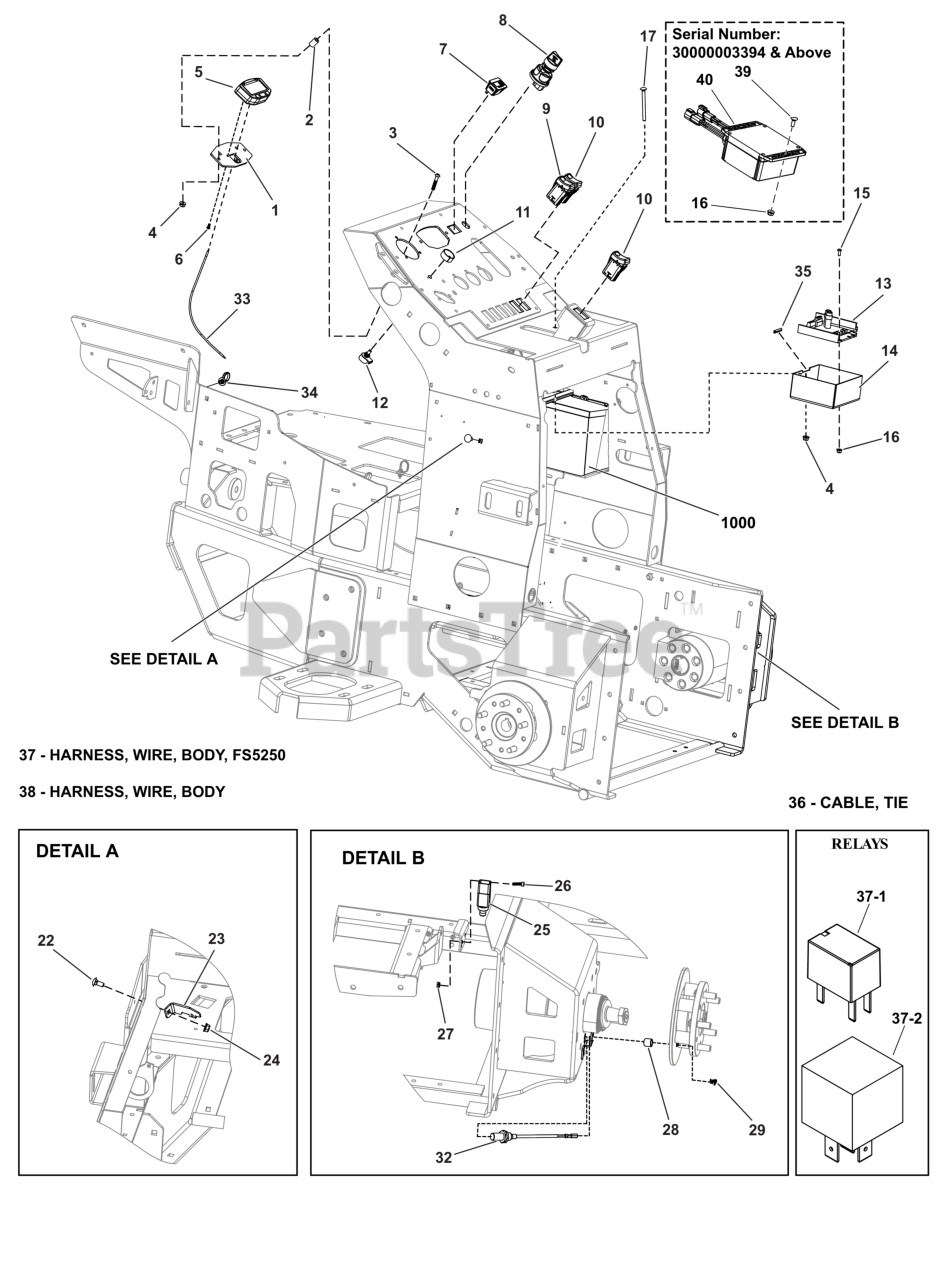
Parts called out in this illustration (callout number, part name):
1	MOUNT, DISPLAY
2	SPCR-SS, 304 .252 X .500 X .750
3	SCR-CAP, SBH .250-20 X 1.500" SS188
4	NUT-HEX-NYLK, FLG .250"-20 SS188
5	DISPLAY, CONSOLE
6	SCR-CAP, SBH M4-0.7 X 10MM SS188
7	METER, TACH/HOUR INDUCTIVE PICKUP
8	SWITCH, IGNITION, IP67 RATED, 3 POS
9	SWITCH, PANEL MOUNT, ON(MOM)-OFF
10	SWITCH, PANEL MOUNT ROCKER ON-OFF
11	KNOB, DART SPEED CONTROL
12	POTENTIOMETER, SPEED CONTROL 5K OHM
12	POTENTIOMETER, 10K OHM, 11 DETENT
13	DRIVE, GEARMOTOR, 12V, 17.5" WIRE LENGTH
14	COVER, DART CONTROLLER
15	SCR-CAP, BSH #10-24 X .500" SS188
16	NUT-HEX-NYLK, FLG .#10-24 SS188
17	BLT-RDHDSQNK, .250"-20 X 3.000" SS188
22	BLT-RDHDSQNK, .3125"-18 X .750" SS188
23	BRKT, BRICK HOUSE
24	NUT-HEX-NYLK, FLG .3125"-18 SS188
25	SWITCH, PLUNGER, SEALED MOLEX (NO)
26	SCR-CAP, SH #10-24 X .625" SS188
27	NUT-HEX, KEPS #10-24 SS188
28	MAGNET, WHEEL SPEED SENSOR
29	SCR-CAP, SBWH #10-24 X .375" SS188
32	SENSOR, SPEED, 8MM X 53 IN LG
33	CABLE EXTENSION, SPEED SENSOR, 48"
34	CABLE TIE, NYLON, PUSH-IN, 8" OAL
35	TRIM, U-CHANNEL .031"X.156"X1.25" LONG
36	CABLE TIE, .188" W X 7.50" LNG
37	HARNESS, WIRE, BODY, FS5250
37-1	RELAY, HFV9-G, 35A/20A, 2.8MM TERM
37-2	RELAY, MINI, SLD, RESIST, 50A/30A, SPDT
38	HARNESS, WIRE CONSOLE
39	BLT-RDHDSQNK .250"-20 X .750" SS188
40	ASSEMBLY, DC MOTOR CONTROL
1000	Refer to: Electrical Group - Batteries and Cables
